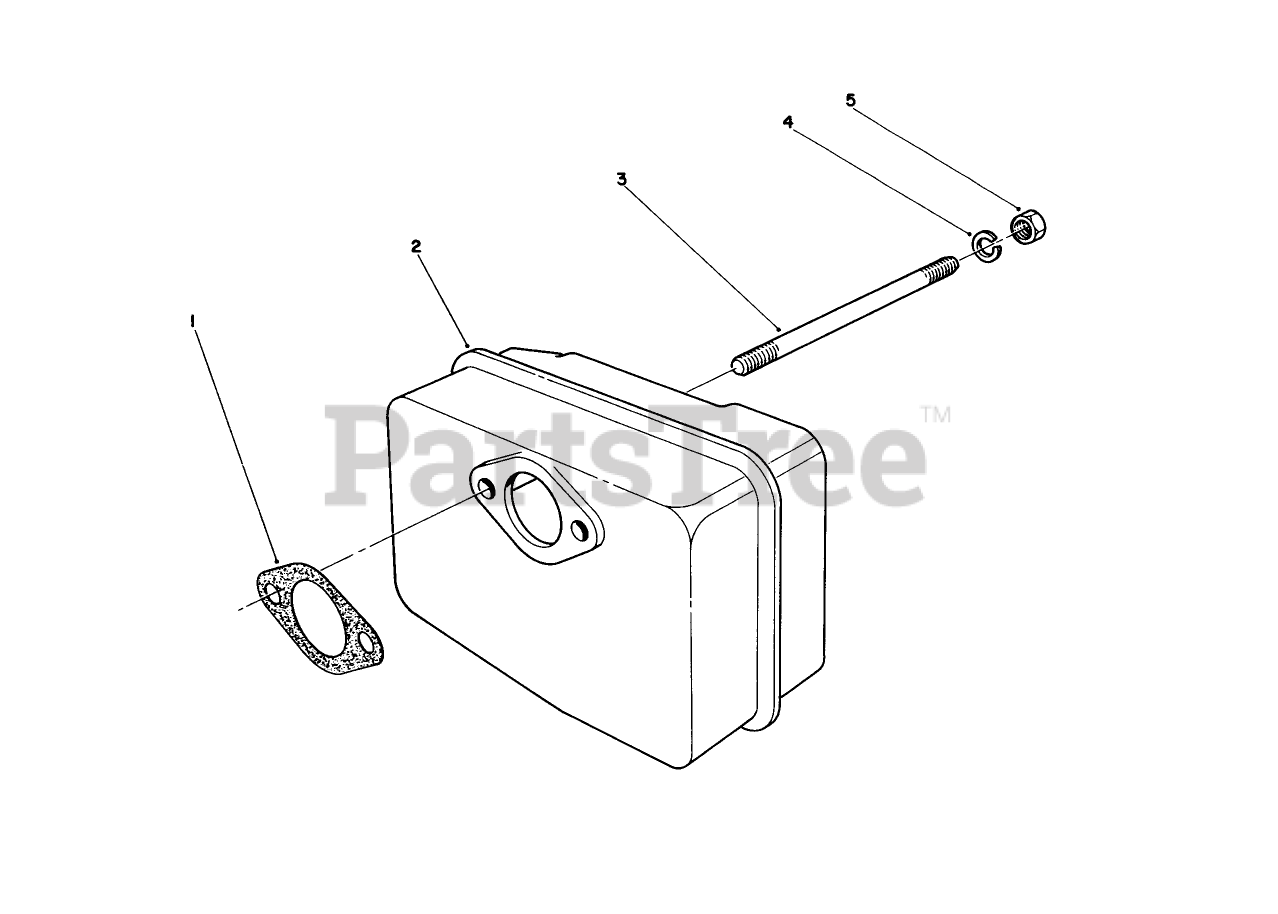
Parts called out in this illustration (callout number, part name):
1	GASKET
2	MUFFLER
4	WASHER-LOCK
